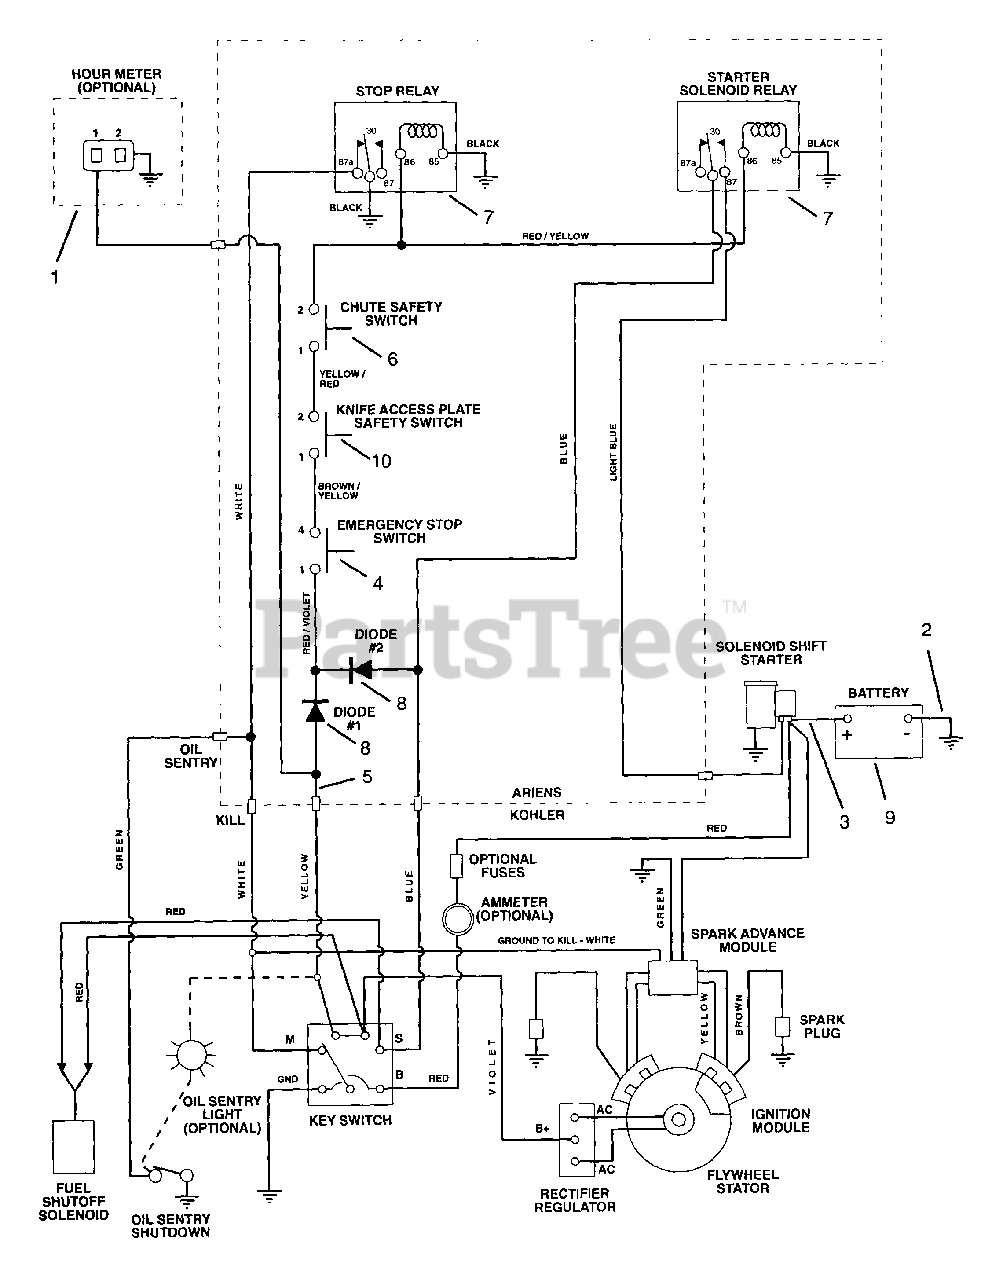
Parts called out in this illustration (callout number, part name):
1	Accessory-Hour Meter
2	Battery Cable (Positive)
3	Battery Cable (Negative)
4	Switch Push/Pull
4	Switch, Clutch with Retainer
5	Harness-Wiring
6	Switch, Sealed Safety
7	Relay
8	Diode
10	Switch, Knife Access Plate Safety
